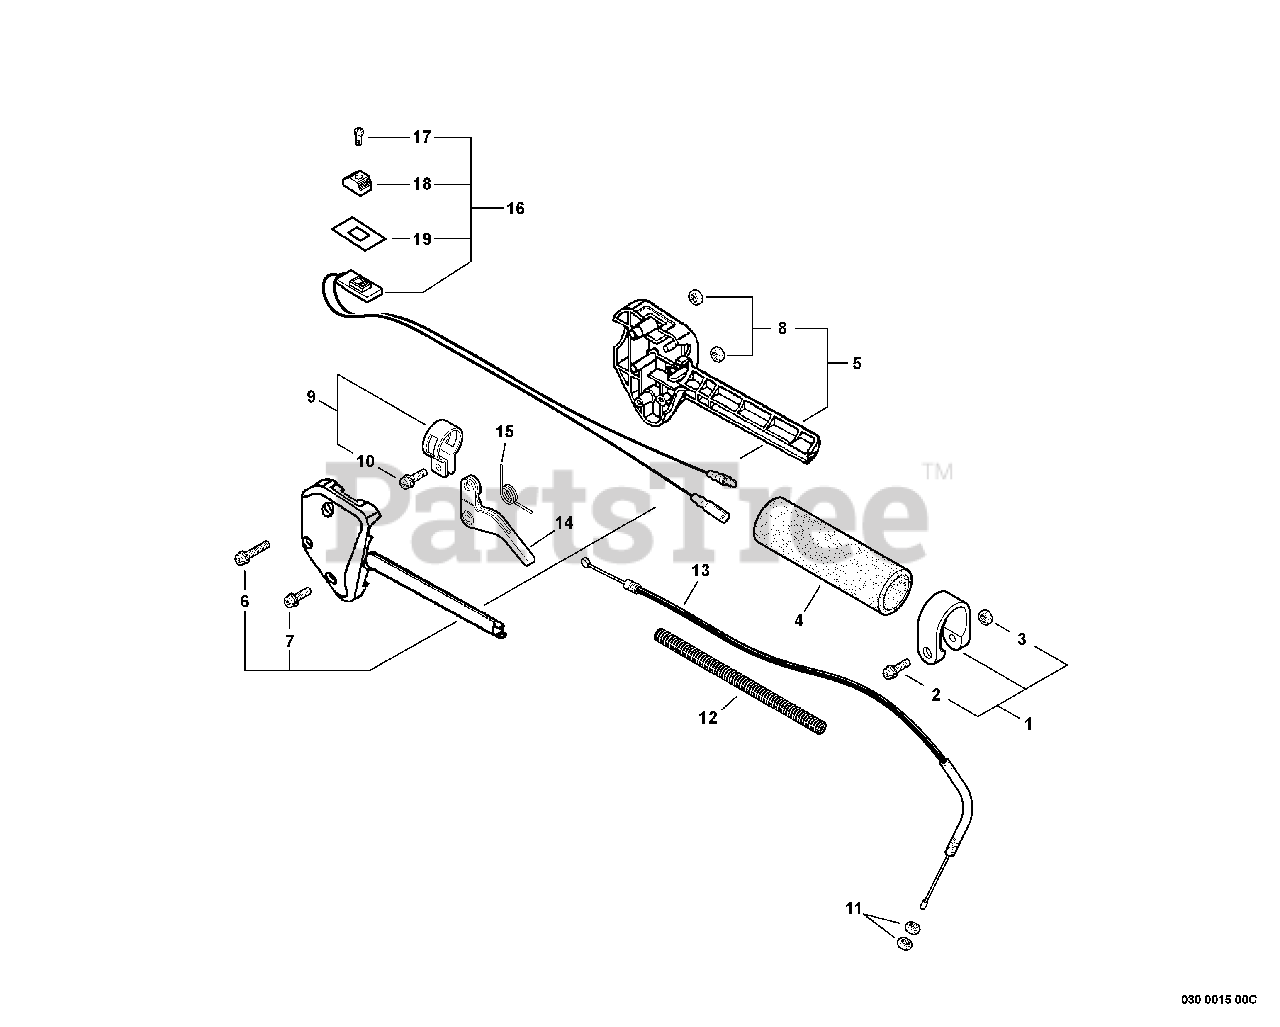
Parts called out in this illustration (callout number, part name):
1	CLAMP KIT
2	SCREW - 5X28
4	GRIP, HANDLE
5	CONTROL HANDLE KIT
6	SCREW - 5X35
7	SCREW - 5X25
9	CLAMP KIT
10	SCREW - 5X14
12	TUBE - VINYL
13	CABLE, THROTTLE
14	TRIGGER, THROTTLE
15	SPRING, TRIGGER
16	IGNITION SWITCH ASSY
17	SCREW - 3X10
18	KNOB, SWITCH - ORANGE
19	COVER, SWITCH - STOP
